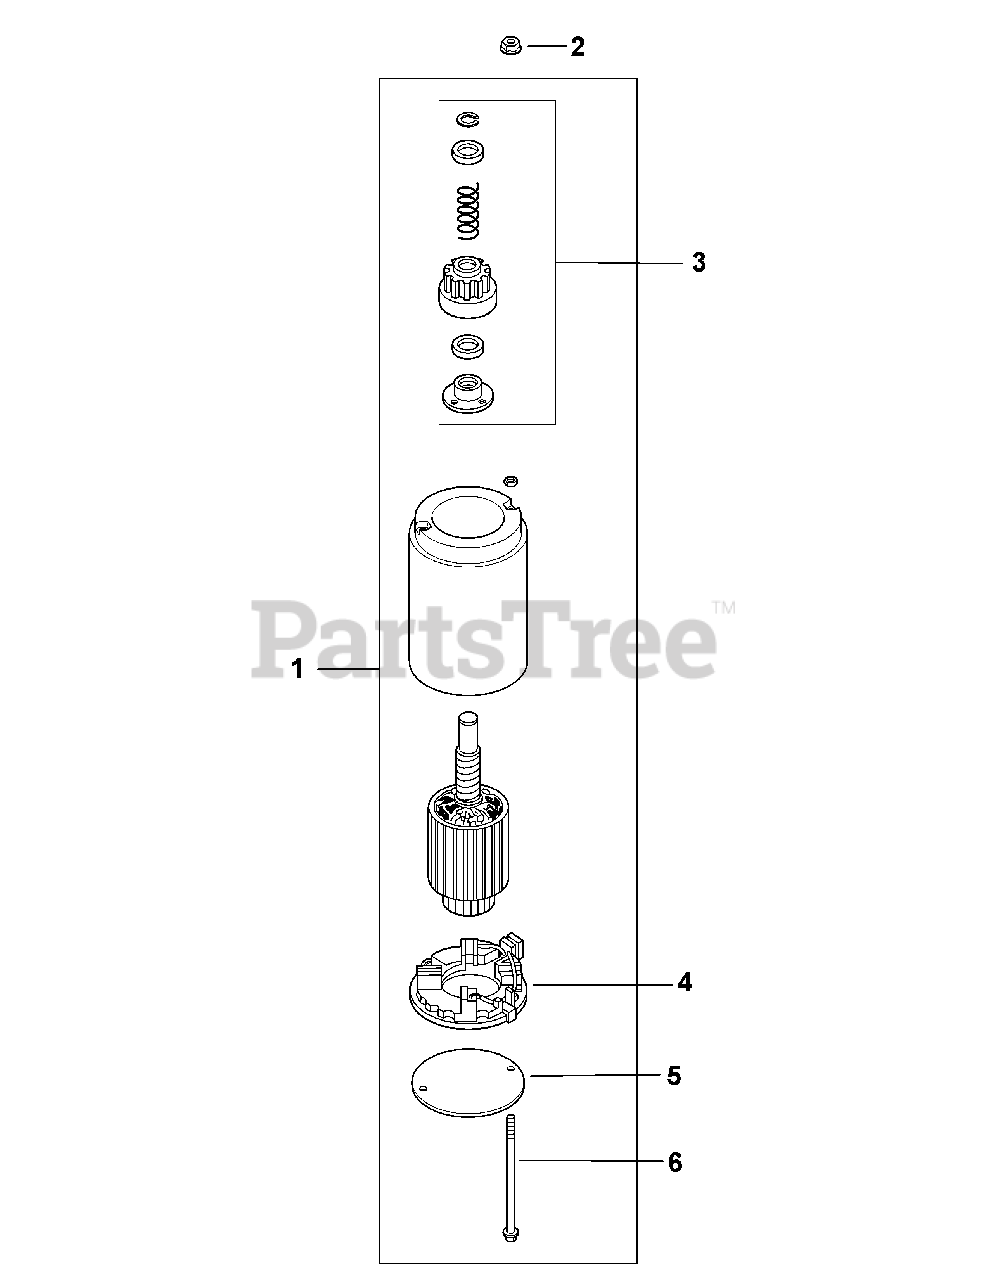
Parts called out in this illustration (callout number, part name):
1	Starter Assembly (Inc. 3-6)
2	Free Spinning Flg. Nut, #10-24
3	Drive Kit (J.E.)
5	Drive End Cap (J.E.)
